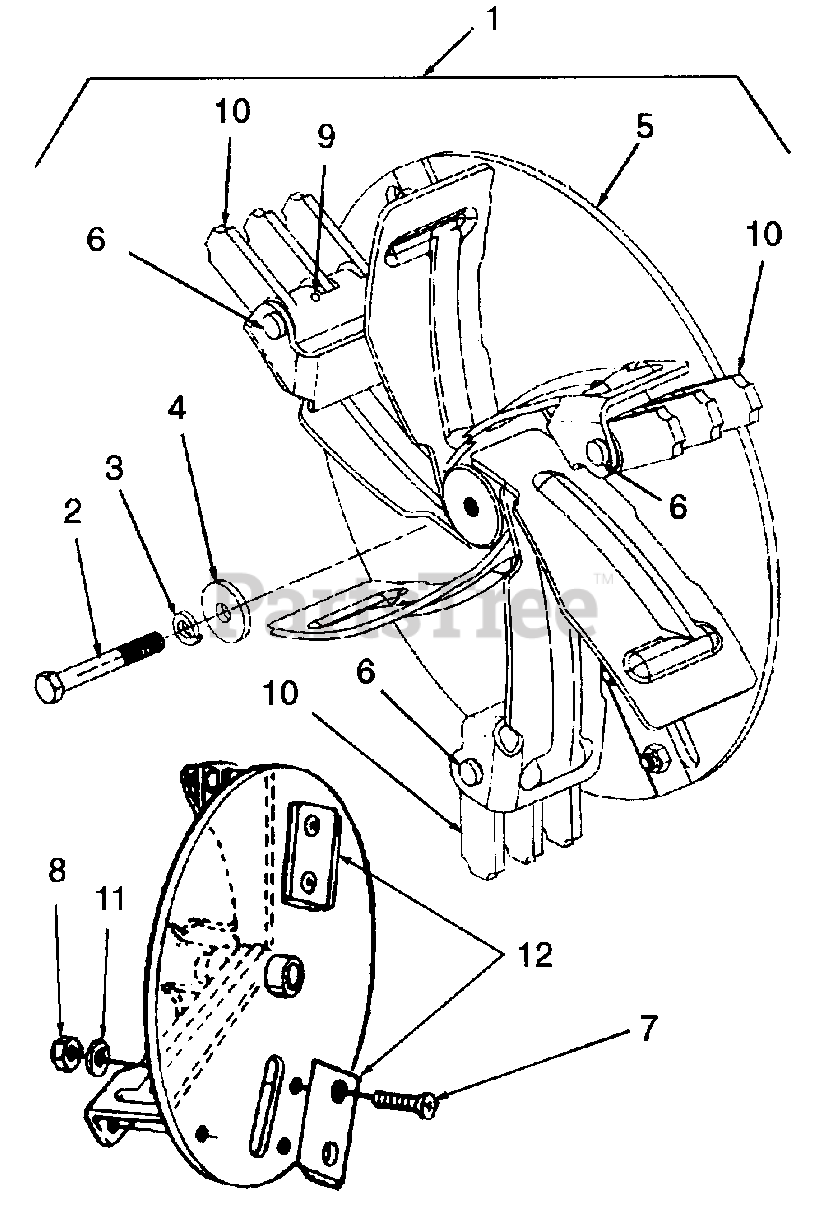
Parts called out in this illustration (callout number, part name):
1	Impeller Ass'y, Complete (CVS24)
2	Screw, Hex Cap, 3/8-24 x 2.75 GR5
3	Washer, Lock, 3/8 Heavy Duty
4	Washer, Flat, .406 x 1-1/4 HD
5	Impeller Assembly (CVS24)
6	Pin, Clevis
7	Screw, Flat Hd. Cap, 5/16-24 x 1.0
8	Nut, Hex Insert Lock, 5/16-24
9	Pin, Spirol, 5/32 x 1.125
10	Blade, Flail
11	Washer, Lock, 5/16
12	Blade, Chipper
